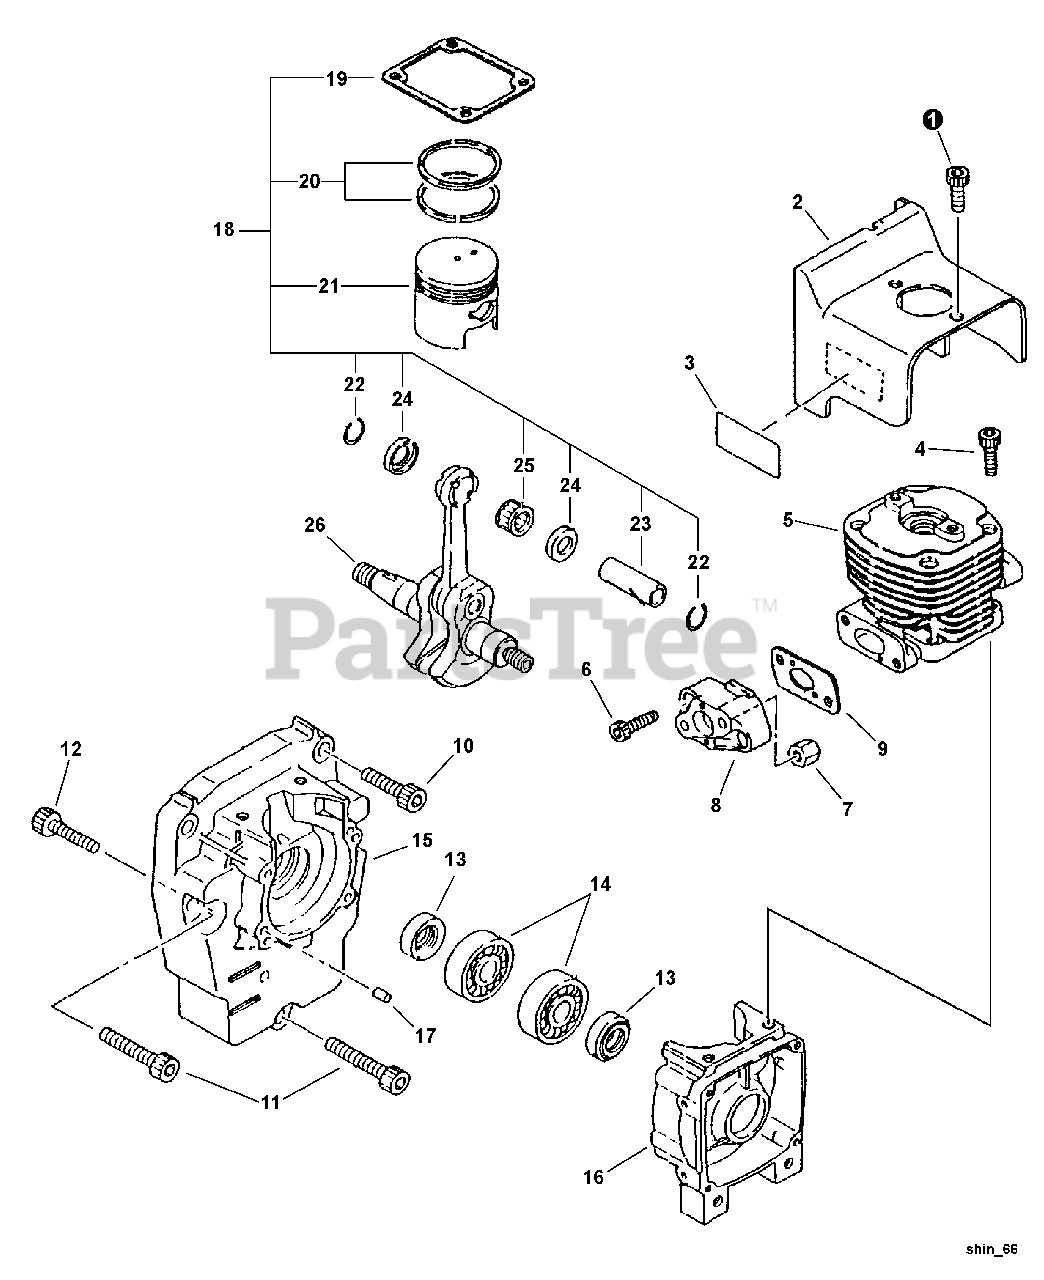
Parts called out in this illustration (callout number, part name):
1	SCREW - 5X14
2	COVER, ENGINE
3	LABEL
4	SCREW - 5X20
5	CYLINDER
6	SCREW - 5X25
7	NUT
8	INSULATOR
9	GASKET, INTAKE
10	SCREW - 6X30
11	SCREW - 6X40
12	SCREW - 5X30
13	SEAL, OIL
14	BEARING, BALL - 6202
15	CRANKCASE - FRONT
16	CRANKCASE - REAR
17	PIN - LOCATING
18	PISTON KIT
19	GASKET, CYLINDER
20	RING, PISTON
21	PISTON
22	RING, RETAINING - 8
23	PIN, PISTON
24	WASHER
25	BEARING, NEEDLE
26	CRANKSHAFT ASSY
